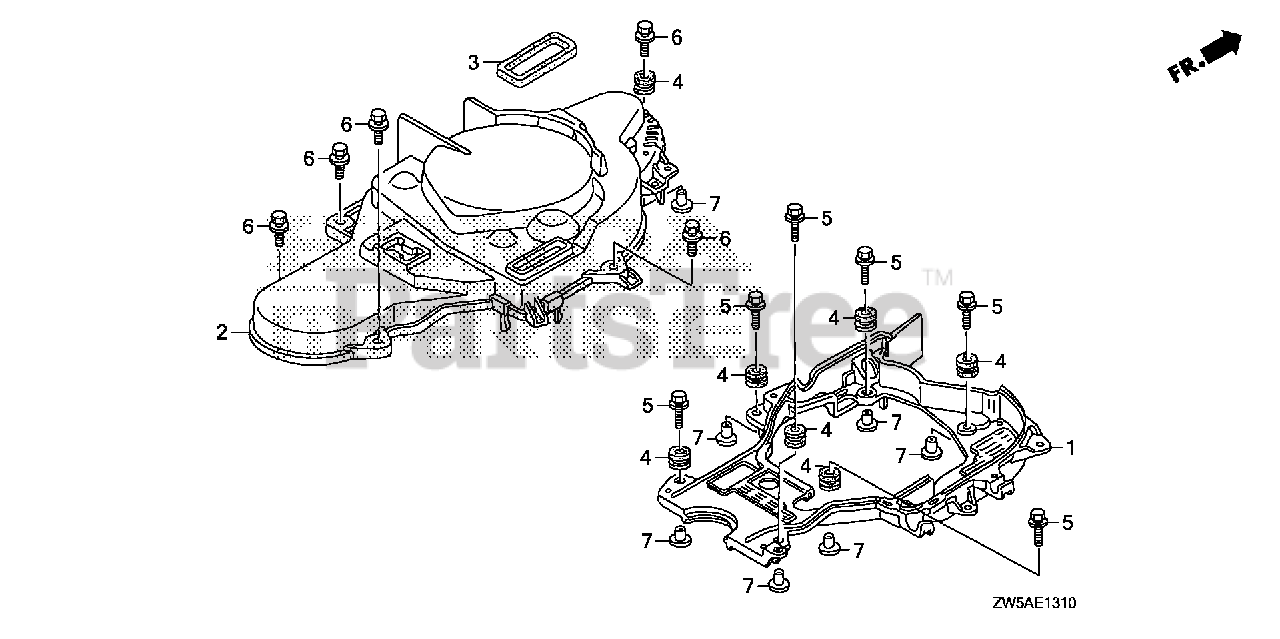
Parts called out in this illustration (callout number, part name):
1	COVER, TIMING BELT (LOWER)
2	COVER, TIMING BELT (UPPER)
3	RUBBER, SEAL
4	GROMMET, CASE (LOWER)
5	BOLT-WASHER (6X27) (CT200)
6	BOLT-WASHER (6X25)
7	COLLAR, MODULE IGNITION CONTROL CASE (CDI)
